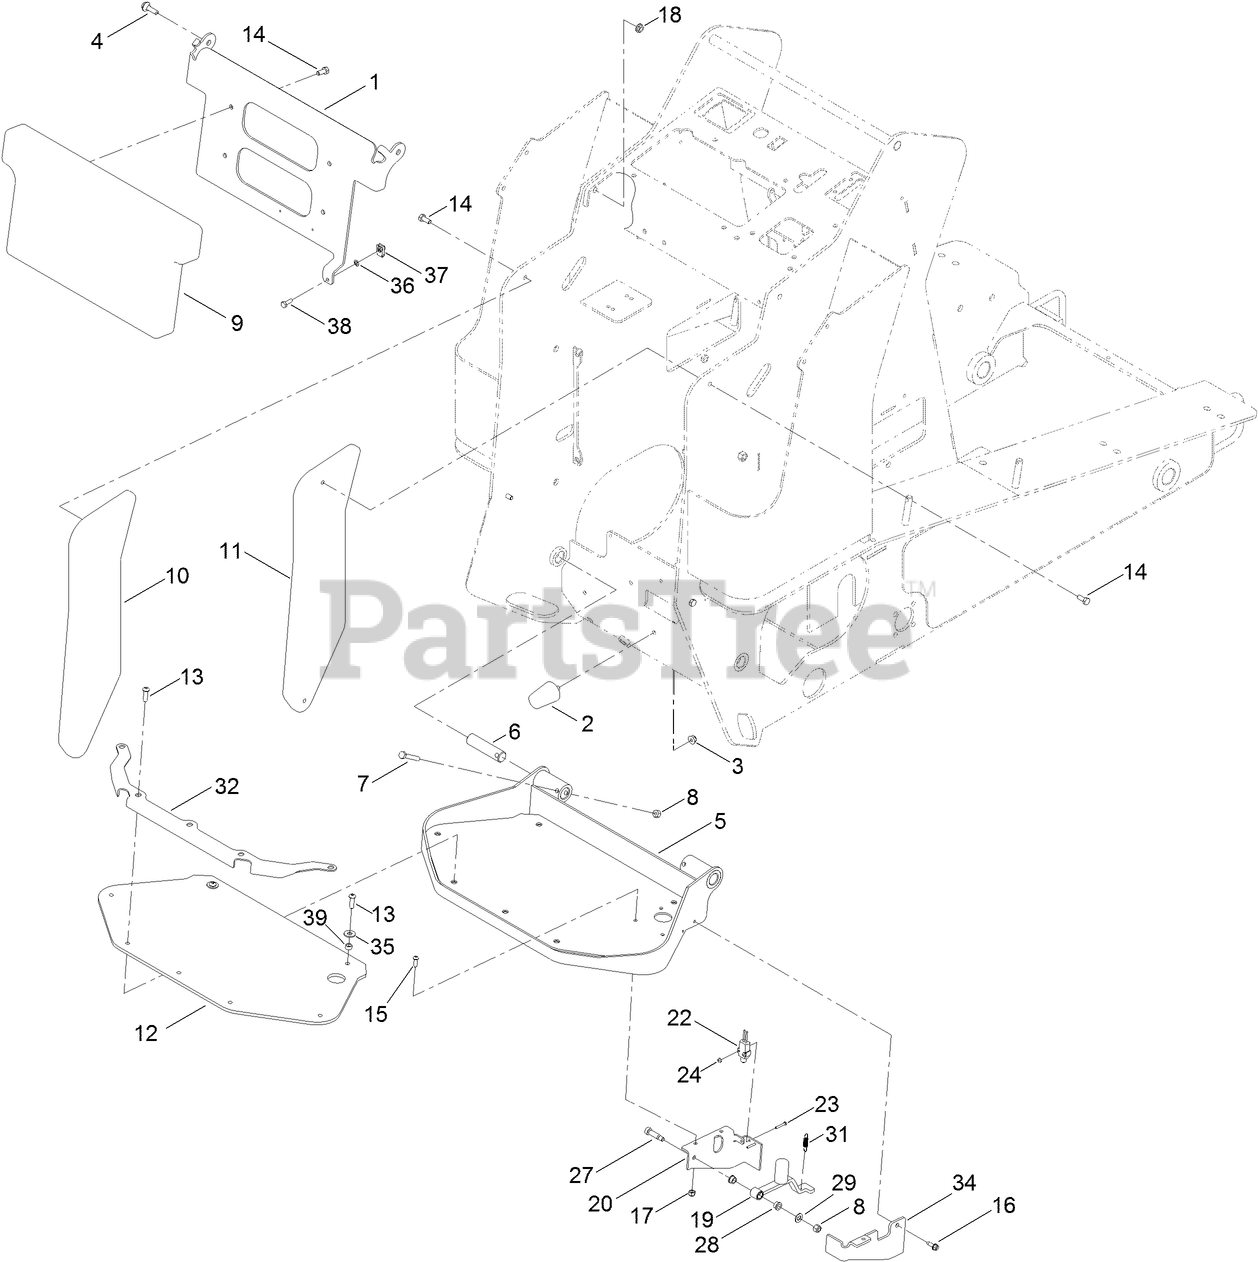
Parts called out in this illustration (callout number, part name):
1	HINGE-PAD
2	BUMPER
3	NUT-HF, NI
4	SCREW-SHOULDER
5	PLATFORM
6	PIN-PIVOT
7	SCREW-HH
8	NUT-LOCK, NI
9	CUSHION-PAD
10	CUSHION-PAD
11	CUSHION-PAD
12	PAD-FOOT
13	SCREW-HSBH
14	SCREW-HH
15	SCREW-HSBH
16	SCREW-HWH, THREAD ROLL
17	NUT-LOCK, NI
18	NUT-HF
19	LEVER-SWITCH, AUXILIARY
20	BRACKET-SWITCH, LH
22	SWITCH
23	SCREW
24	NUT-HEX
27	BOLT-SHOULDER
28	BUSHING-FLANGED
29	WASHER-FLAT
31	SPRING
32	PLATE-CLAMP
34	BRACKET-SWITCH, RH
35	WASHER-FLAT
36	NUT-RETAINING
38	SCREW-HH
39	SPACER-PIVOT, TILT
